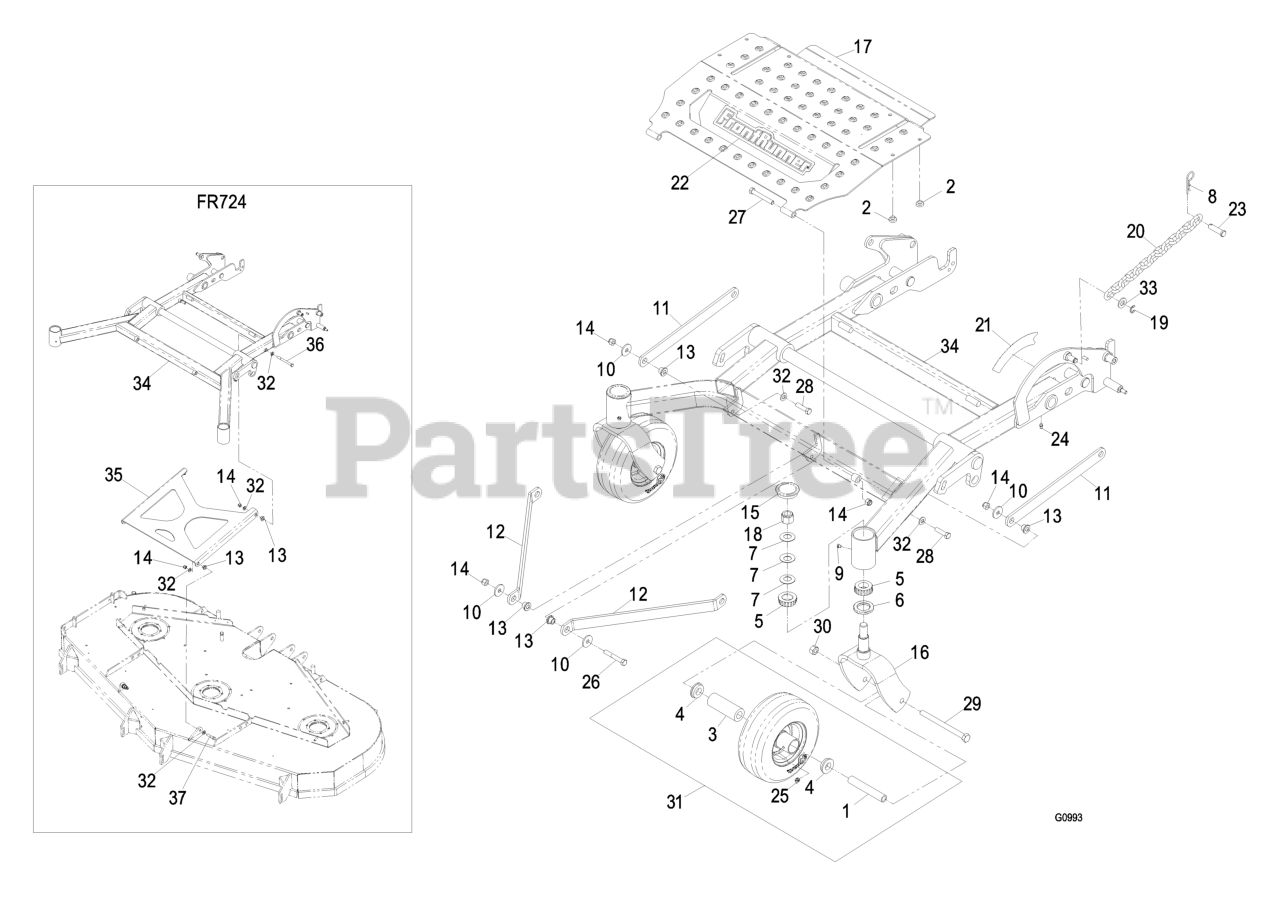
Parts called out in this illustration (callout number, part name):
3	BEARING
4	BUSHING
5	Cone-Bearing Tapered Roller
6	SEAL-GREASE
7	WASHER-BELLVILLE
8	PIN-COTTER
11	FLAT,STRUT
12	FLAT,STRUT ANGLED
13	SPACER-STRUT
14	NUT-LOCK, NI
15	CAP-GREASE
16	WLD,CASTER FORK FMZ
17	ASM,FRONT COVER W/DECAL
18	NUT-LOCK, NI
19	RING-RETAINING, EXTERNAL
21	DECAL,DECK HEIGHT
22	DECAL,FRONTRUNNER
23	PIN-CLEVIS
24	FITTING-GREASE
25	FITTING-GREASE
26	BOLT-CARR
27	SCREW-HH
28	SCREW-HH
29	SCREW-HH
30	NUT-HEX
31	KIT, SP CASTER WHEEL REPL
32	WASHER-FLAT
33	WASHER-FLAT
34	ASM,FRONT FRAME W/DECAL 5
36	SCREW-HH
37	SCREW-HH
